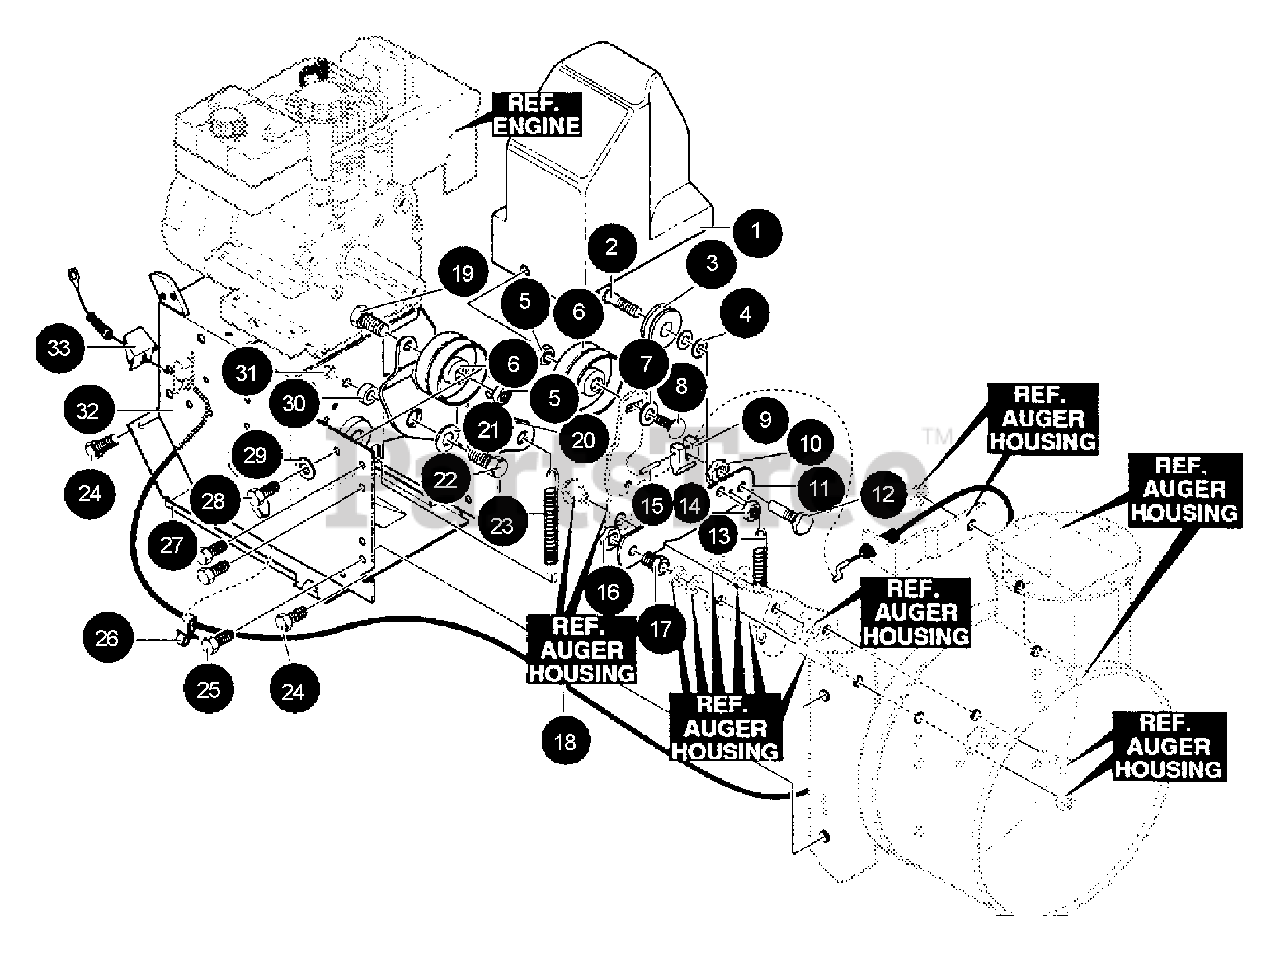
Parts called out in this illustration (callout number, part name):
1	COVER, BELT
2	BOLT - 0.375×0.375 HHSH 1/4-20
3	PULLEY
4	WASHER
5	LOCKNUT - 3/8-16
6	PULLEY, IDLER
7	WASHER - 0.506×0.75×0.024"
8	BOLT, 3/8-16×1.25 CARR
9	PAD, AUGER/IMPELLER BRAKE
10	LOCKNUT - 1/2-20
11	BRACKET
12	BOLT, BRAKE ARM
13	SPRING, IDLER BRAKE
14	NUT, 1/4"-20
15	PIN, SPRING
16	NUT, 9/16-18 JAMCTRLK
17	BOLT, BRAKE ARM 9/16-18
18	CABLE, AUGER
19	SCREW - 3/8-16×1.25" -- HEX HEAD CAP
20	LEVER, IDLER ARM TRACTION
21	WASHER, FLAT 0.328×1.25×0.075
22	SCREW 5/16"-18×0.75
23	SPRING, IDLER
24	SCREW 1/4"-20×0.63
25	SCREW, 5/16-18×0.50 WAHHTAP
26	CLIP, CABLE TINN #D98281-017
27	COVER, BOTTOM
28	WASHER
29	BUSHING, IDLER LEVER
30	NUT, 5/16 - 18
31	FRAME ASSY
32	SHIELD, CABLE GUARD
